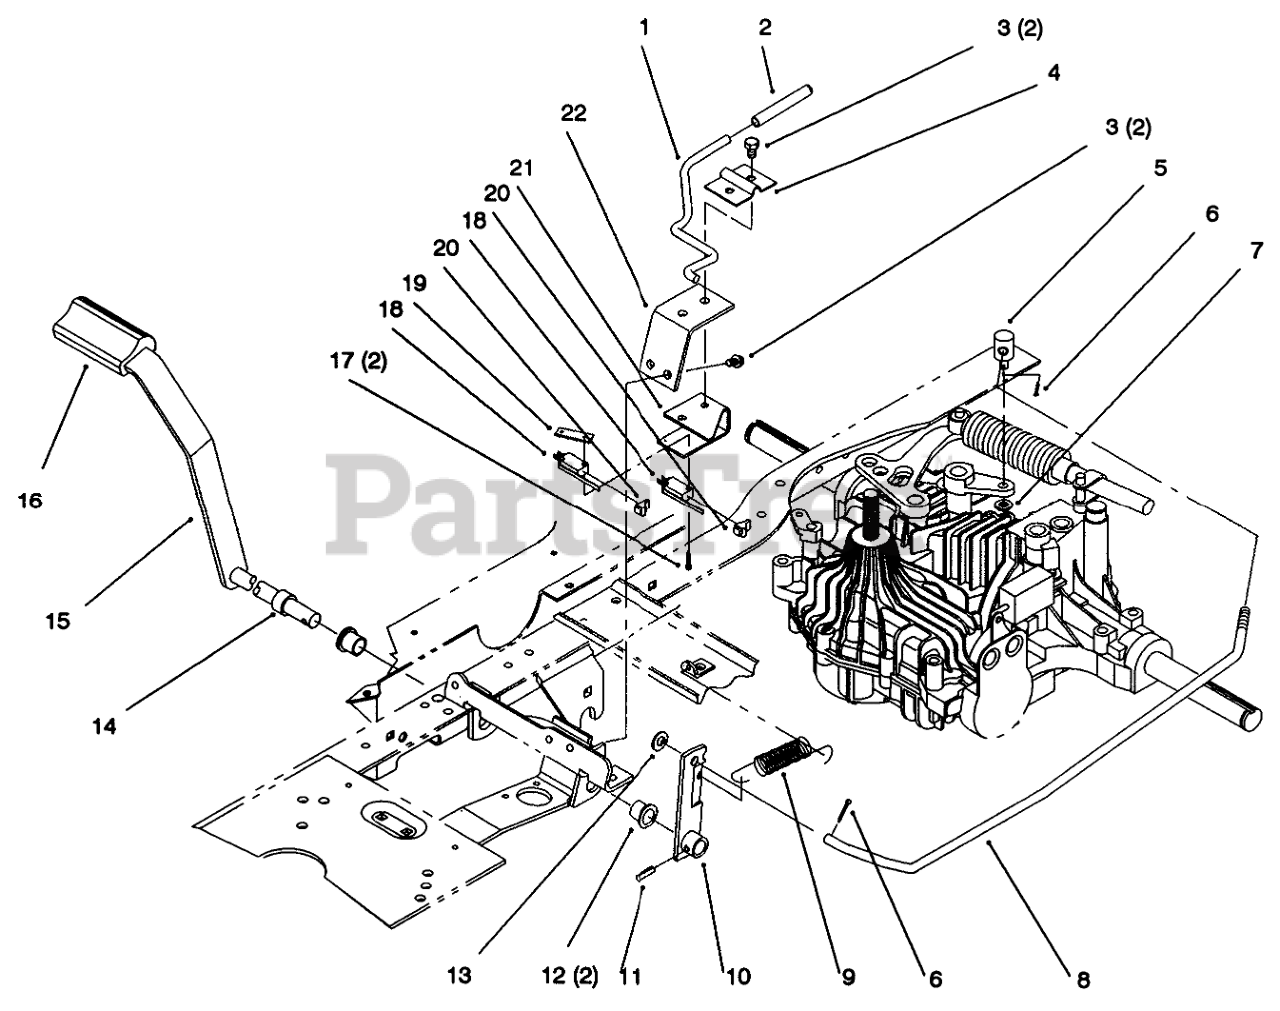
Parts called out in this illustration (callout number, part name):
1	ROD - PARKING BRAKE
2	GRIP - PARKING BRAKE
3	SCREW-HWHTF
4	Bracket-Park Brake
5	TRUNNION - BRAKE
6	PIN-COTTER
7	WASHER-PLAIN
8	ROD - BRAKE
9	SPRING-EXTENSION
10	Lever-Brake
11	PIN-SPRING
12	BUSHING-FLANGE
13	WASHER-FLAT
14	SPACER-BRAKE
15	Brake Pedal Wa
16	PAD-PEDAL
16	Tube-Brake
16	Lever-Brake
17	SCREW-HH
18	SWITCH-MICRO
19	NUT-SPEED
20	PLUNGER-SEAL
21	Bracket-Micro Sw
22	Support-Park Brake
